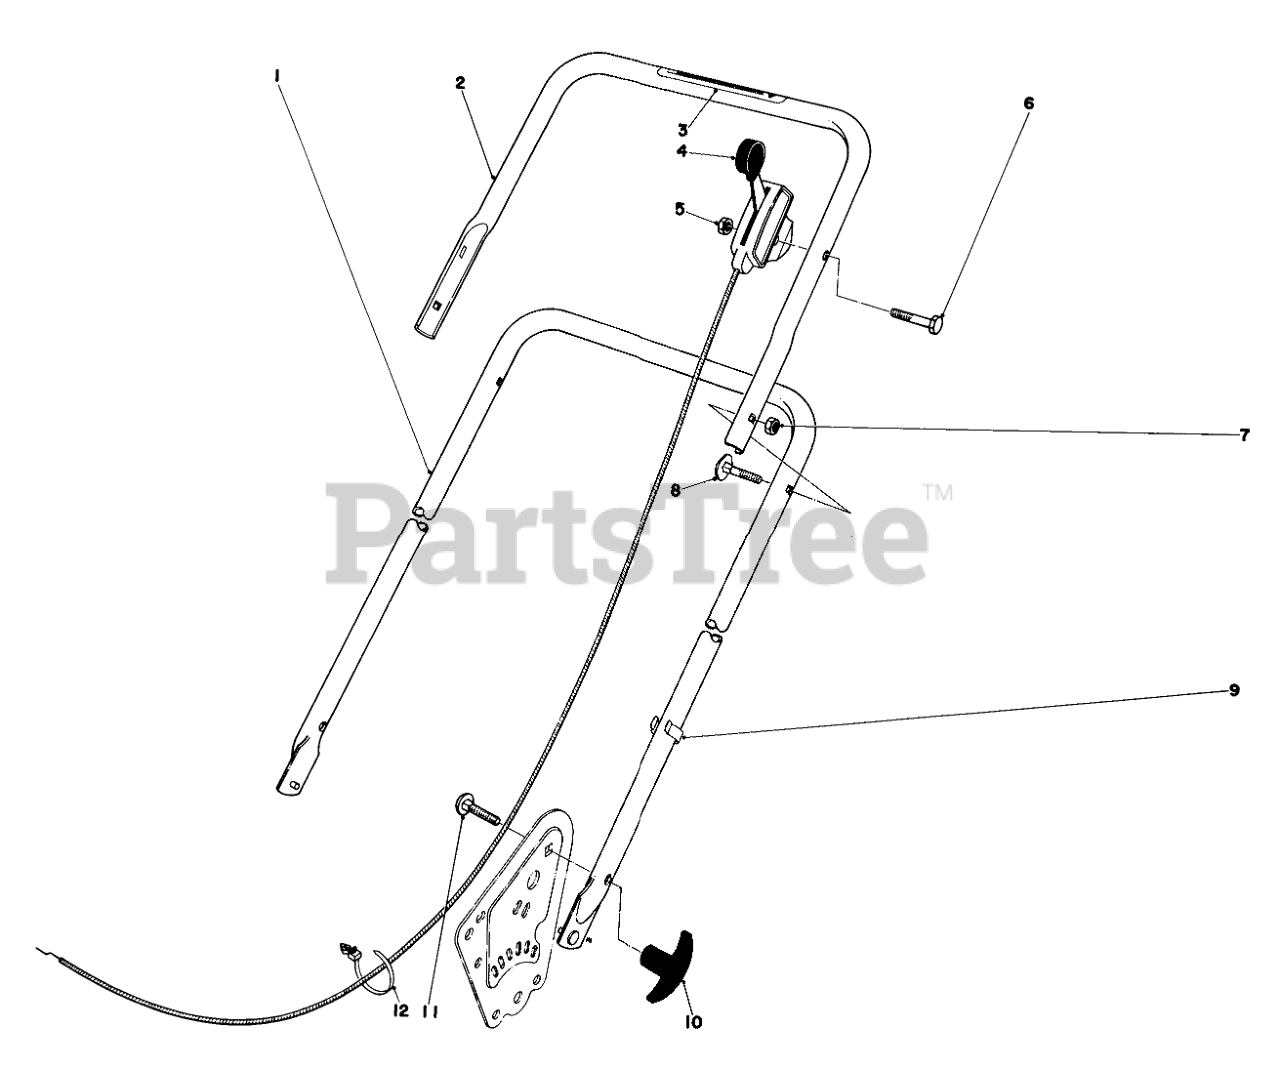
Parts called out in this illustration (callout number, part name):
1	Lower Handle
2	Upper Handle
3	Decal
4	Throttle Control
5	NUT-LOCK
6	SCREW-HH
7	Nut
8	HANDLE SCREW
11	BOLT-CARR
12	TIE-MOUNT, PUSH
